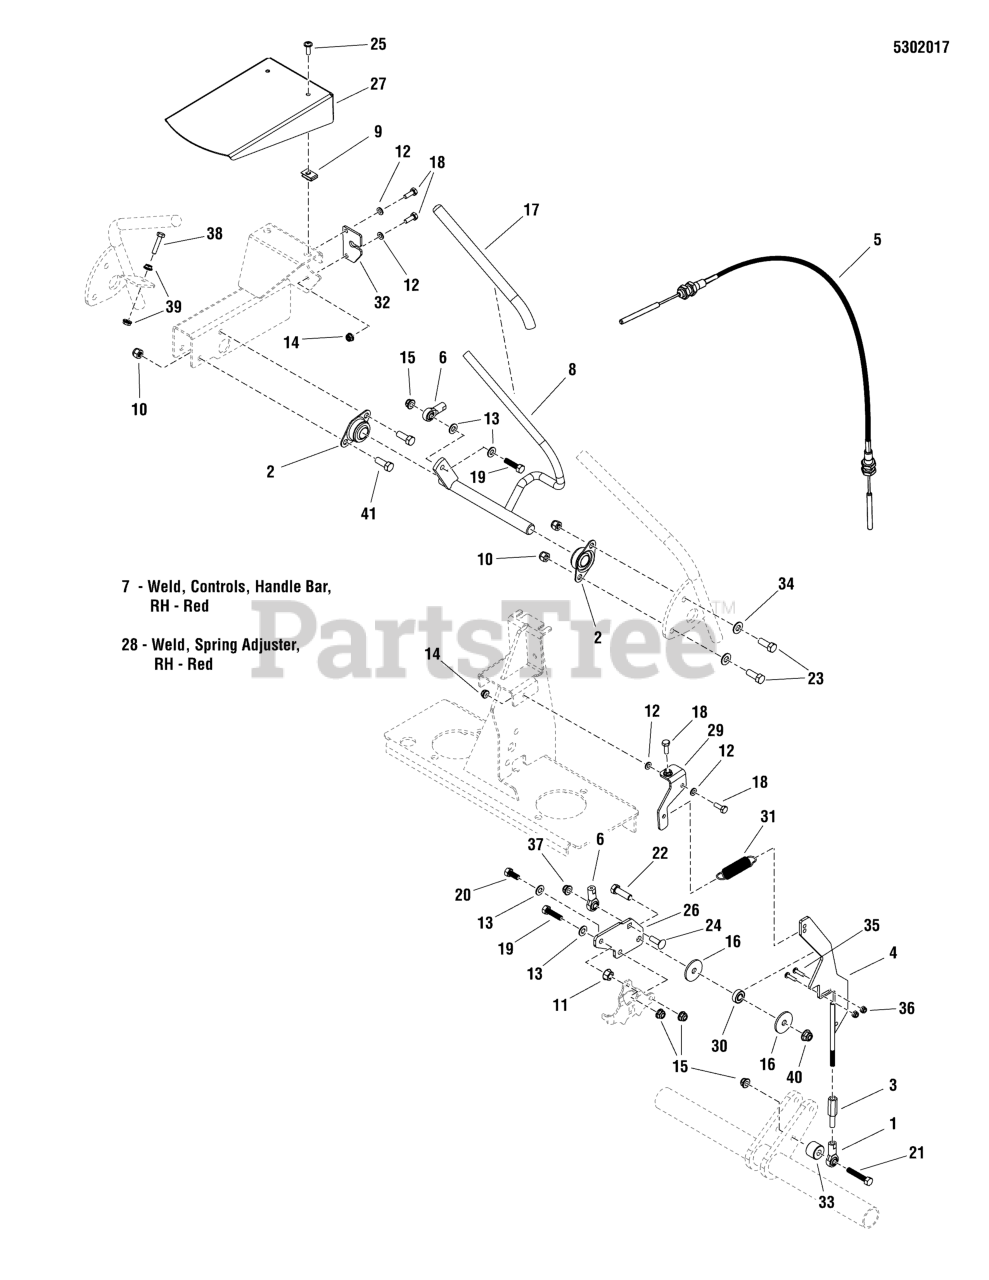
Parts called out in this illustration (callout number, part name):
1	BALL JOINT 5/16-24 RH FEMALE STAMPED STL
2	BEARING, BRONZE FLANGE, 3/4"
3	ADJUSTER, ROD LINKAGE 5/16-24
4	WELD, CONTROL RAMP, EVO
5	CABLE, PUSH/PULL, 30" SPEED CONTROL
6	ROD END, FEMALE, 10-32 W 5/16" BORE
8	WELD, CONTROLS, HANDLE BAR, LH, EVO
9	BODY CLIP, 1/4-20 X 1/2 DEEP
10	NUT, 3/8-16 HEX NYLON LOCK
11	NUT, 5/16-18 HEX SERRATED FLANGE (SMALL)
12	WASHER, 1/4 SAE
13	WASHER, 5/16" SAE
14	NUT, 1/4-20 HEX NYLOCK FLANGE
15	NUT, 5/16-18 HEX NYLOCK FLANGE
16	WASHER, .390 X 1.50 X .109, YZ
17	GRIP, FOAM, .48 x 10 x .125 Black
18	BOLT, 1/4-20 X 3/4 GD5 YZ
19	BOLT, 5/16-18 X 1-1/4 GD5 YZ
20	BOLT, 5/16-18 X 3/4 GD5
21	BOLT, 5/16-18 X 2.00 GD5
22	BOLT, 3/8-16 X 1-1/4" GD5 CZ
23	BOLT, 3/8-16 X 1" GD5 CZ
24	BOLT, 5/16-18 X 1, CARRIAGE
26	PLATE, PUMP CONTROL, 36 - RED
27	PLATE, MOTION CONTROL GUARD - RED
28	WELD, SPRING ADJUSTER, RH - RED
29	WELD, SPRING ADJUSTER, LH - RED
30	BEARING, .375" ID X .875" OD X .341" THK
31	SPRING-EXT, 3.281 x .751 x .075 WIRE
32	PLATE, CABLE - RED
33	SPACER, .39 X 1.00 X .75
34	WASHER, 3/8 SAE
35	SCREW, #10-24 X 3/4 ROUND PHILLIPS
36	NUT, #10-24 HEX NYLON LOCK
37	NUT, 5/16-18 HEX NYLON LOCK
38	BOLT, 1/4-20 X 1-1/4, GD5
39	NUT, 1/4-20 HEX SERR. FLANGE
40	NUT, 3/8-16 HEX NYLOCK FLANGE
41	BOLT, 3/8-16 X 3/4" GD5 CZ
42	SHIM, .375" X .625 X .031 THK
